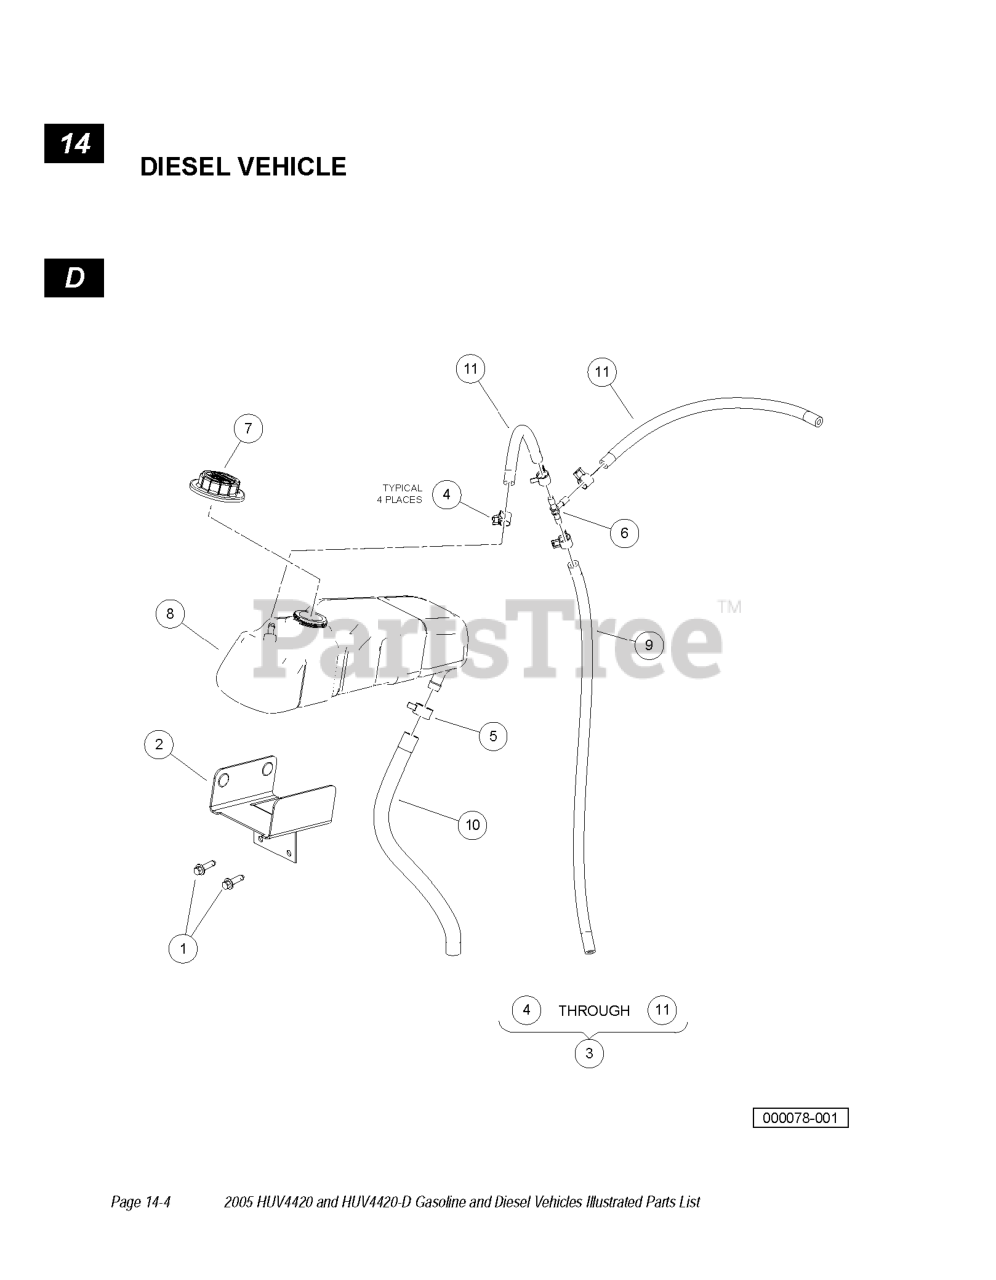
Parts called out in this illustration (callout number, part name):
1	SCREW-M8 X 1.25 30, TRI, HX F
2	BRACKET, COOLANT BOTTLE
4	CLAMP, HOSE, CTB 15MM
5	CLAMP, HOSE, CTB 22MM
6	FITTING, TEE
7	CAP, PRESSURE 14 PSI
8	TANK, EXPANSION
9	HOSE, TEE TO VENT TUBE, COOLNT
10	HOSE, COOLANT FILL
11	HOSE, COOLANT TEE TO BOTTLE
